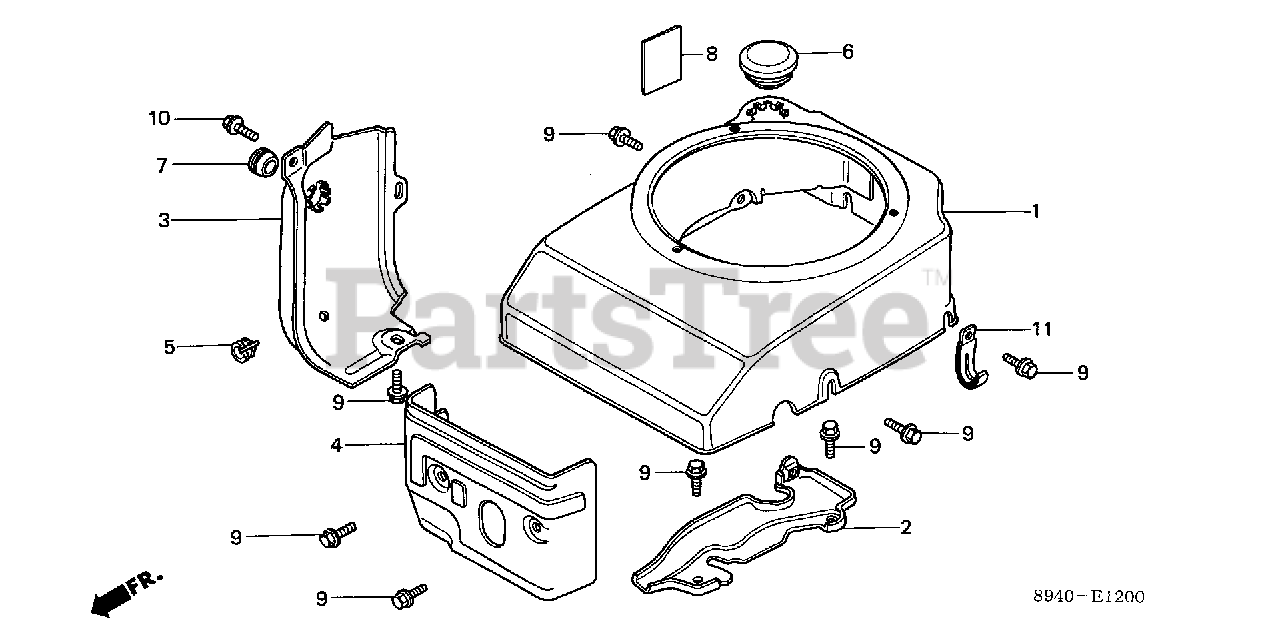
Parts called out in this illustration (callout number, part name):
1	COVER, FAN *R8* (BRIGHT RED)
1	COVER, FAN *NH67* (SPARKLE WHITE)
2	PLATE, SIDE (NOT AVAILABLE)
4	COVER, TOP
7	GROMMET, DRAIN HOLE
8	MARK, OIL CAUTION
9	BOLT, FLANGE (6X12) (CT200)
10	BOLT, FLANGE (6X14) (CT200)
11	CLIP, CABLE
